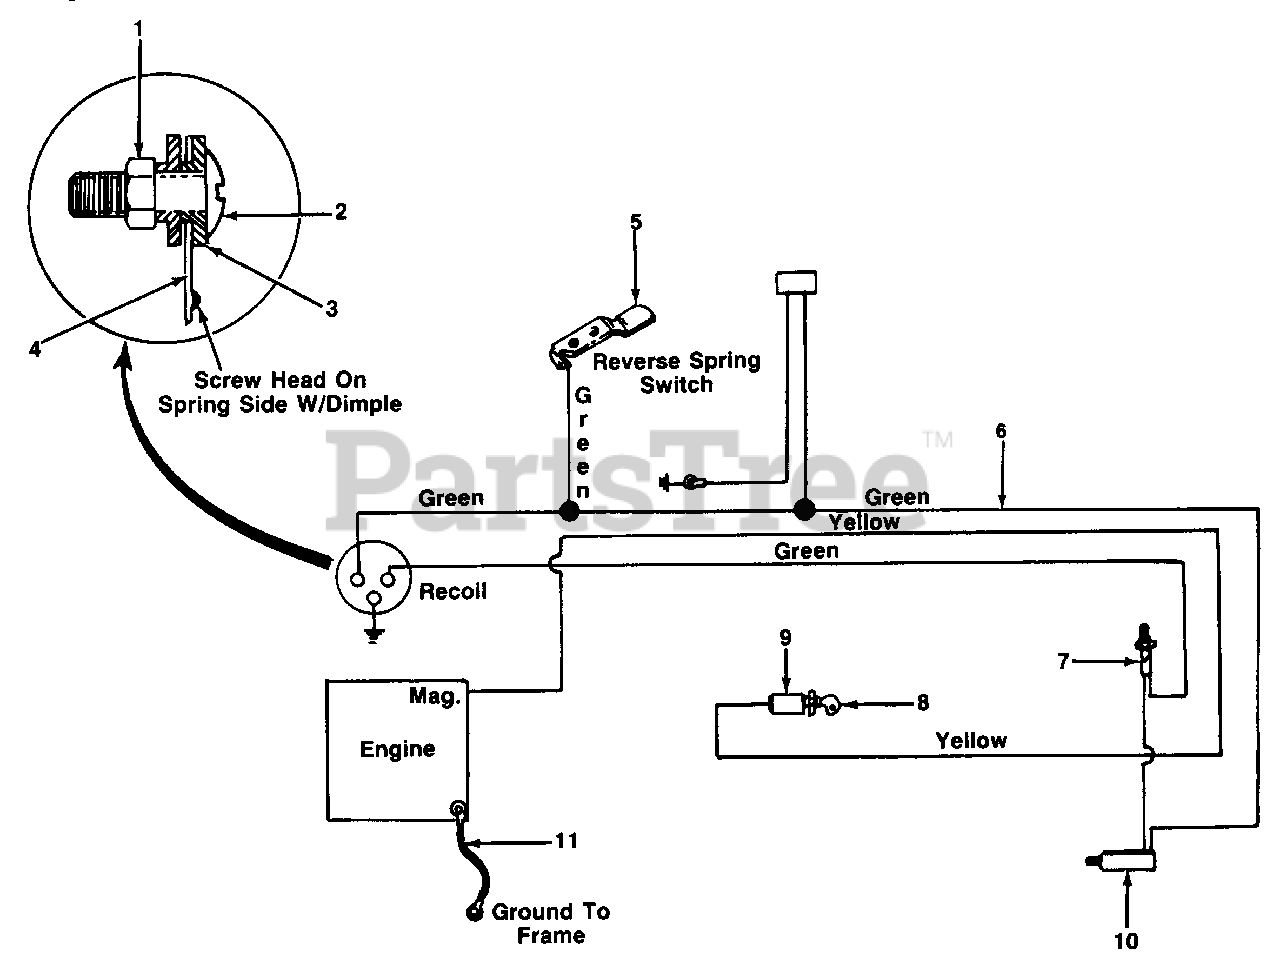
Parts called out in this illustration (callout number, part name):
2	SCREW-TRUSS MACH #10-24 X .62
3	WASHER-FIBER
4	SPRING-SWITCH
5	SPRING-SWITCH
6	WIRE HARNESS
7	SWITCH-SAFETY
8	KEY-IGN (SET OF TWO)
9	SWITCH-KEY TYPE
10	SWITCH-SAFETY
